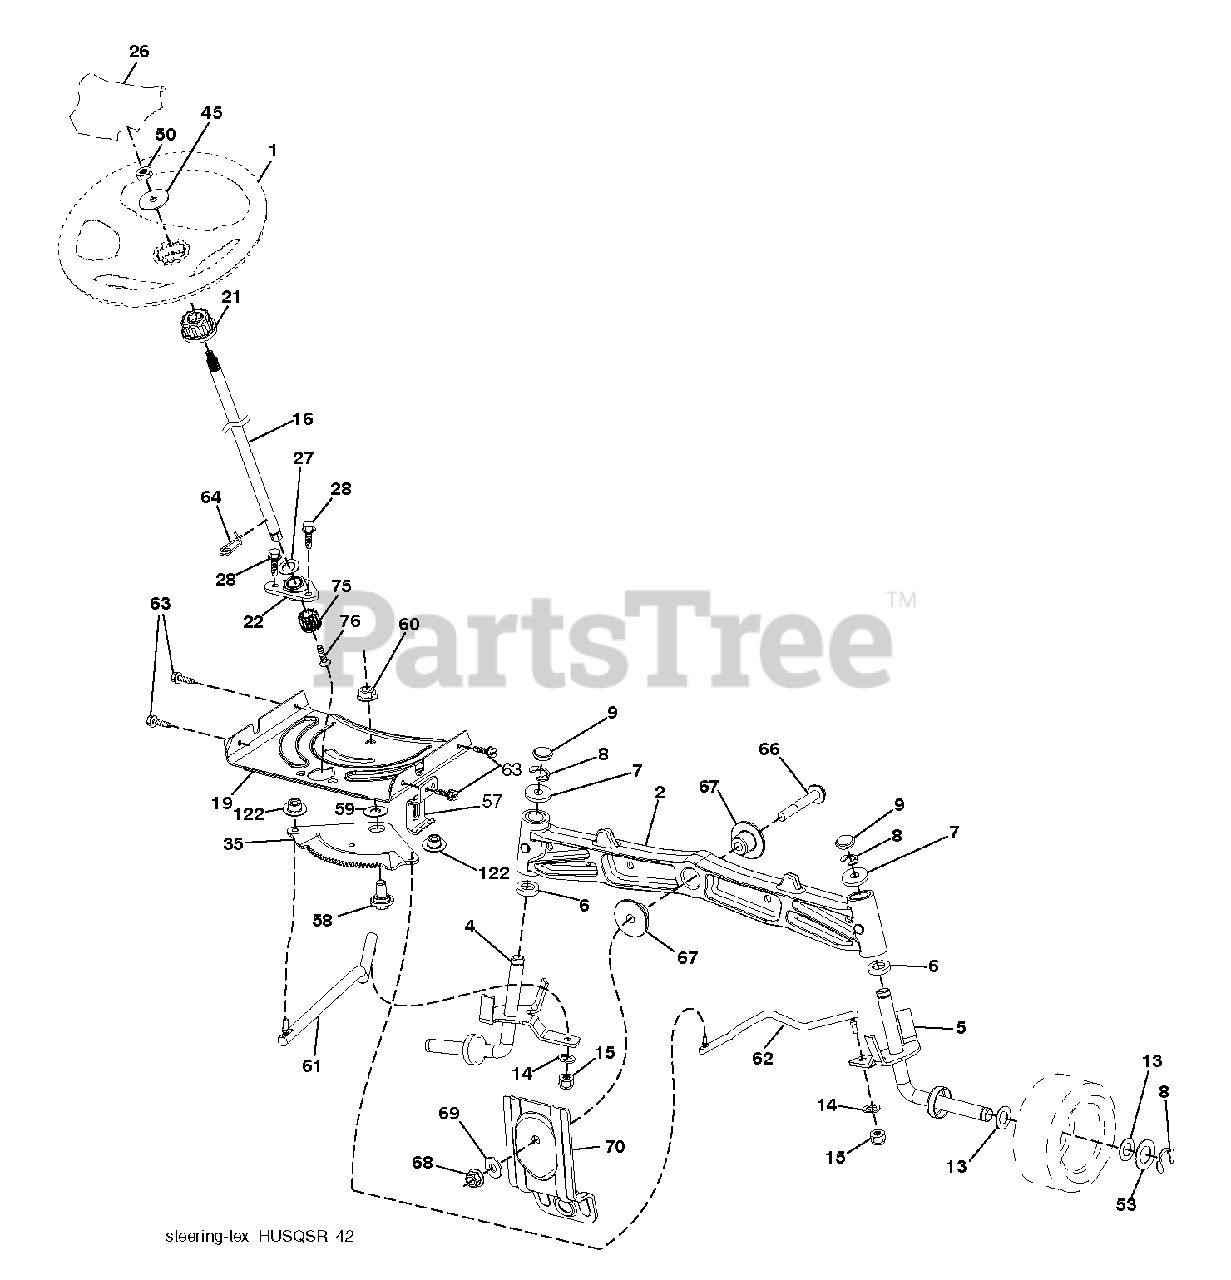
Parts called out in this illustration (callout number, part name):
1	WHEEL.STEER.HUSQ.SR.498.OVMLD
2	AXLE.CAST.IRON
4	SPINDLE.WELDED.LH.16"TEX
5	SPINDLE.WELDED.RH.16"TEX
6	THRUST WASHER
9	CAP.SPINDLE.BLACK
14	WASHER, LOCK 3/8
15	NUT CROWNLOCK 3/8-24
16	SHAFT.STEERING.2HIGH.SPLND.RAW
19	PLATE.STEER.DDL.NLT/NG
21	ADAPTER.WHEEL.STEER.SPLND.ALUM
22	BEARING.SUBASM.SHAFT.STEER.LOW
26	INSERT.CAP.WHL.STRG.HUSQ.PREM
27	WASHER LT
28	SCREW, 3/8-16X3/4
35	GEAR.SECTOR.PLATE.DDL.
45	WASHER.3/8ID.2-3/8OD.12GA.PLTD
50	NUT LOCK FLG 3/8-16 UNC
53	WASHER.HARDENED
57	BRKT.UPSTOP.GT/LT.TEX
58	BOLT.SHOULDER.SECTOR.P
59	WASHER.THURST.SECTOR.S
60	NUT FLANGE LOCK 5/8-11
61	DRAGLINK.LH.BALLSTUD.D
62	DRAGLINK.RH.BALLSTUD.D
63	SCREW
64	RETAINER.CLIP.SPRING.S
66	BOLT HEX FGHD 7/16-14 X 3 SERR
67	BUSHING.PM.FRONT AXLE
68	NUT.LOCK.FLANGE.7/16
69	WASHER.1.5X.505X.118
70	BRACKET.FRT.DECK.SUSP.RR.MT431
75	PINION.ZINC PLATED
76	SCREW HEAD SOCKET LRVB
122	CAP.GEAR.SECTOR.TEX
